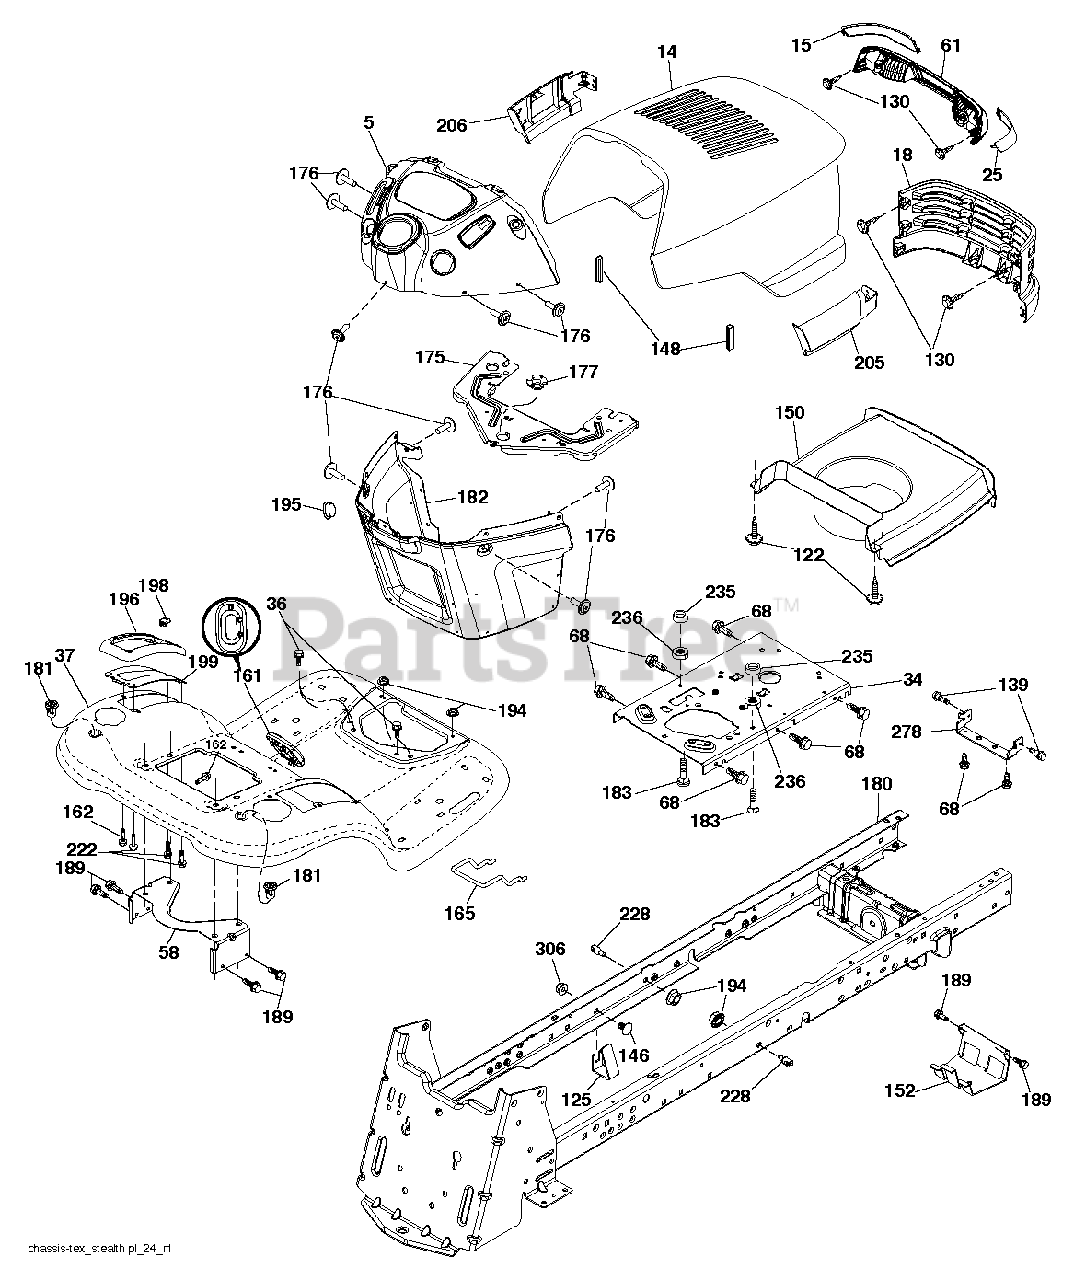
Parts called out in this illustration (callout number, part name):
5	DASH.STEALTH.SRV.RS.428
14	HOOD ASM.STEALTH.HOR-LOUV.667
15	LENS LH
18	GRILLE.STEALTH.GT.BLACK
25	LENS RH
36	SCREW 5/16"
58	BRKT.SUPPORT.FNDR/TANK
122	SCREW.WSHD.HEX10-32X5/8
125	Fuel Line Clip
130	SCREW.#10 X 0.750.BOS THREAD
139	BOLT, SHOULDER 5/16-18
146	BOLT.RDHD.SHT.SQNK.3
148	EXTRUSION BUMPER
152	SHIELD BROWNING
161	CONSOLE.FUEL.WINDOW.STGT.BLACK
162	SCREW.HI-LO.CONSOLE
165	SUPPORT.TANK.REAR.W/TE
175	CROSSMEMBER.
176	SCREW.#10-24X5/8.RN.QU
177	BUSHING,STEERING
180	CHASSIS.GT.SLOPED.DRAWBAR.
181	FEND/FTRST.PCH.CPH.NFW
182	DASH.LOWER.
183	BOLT.5/16-18X1-1/4 FULL THD
189	SCREW
194	NUT LOCK HEX FLANGE 5/16-18
195	PLUG.HOLE.DASH.LOWER.12V.BLK
198	INDICATOR.DECK.LIFT.RED
199	PLATE DECK LIFT
205	SKIRT.GRILLE.STEALTH.RH
206	SKIRT.GRILLE.STEALTH.LH
222	SCREW.1/4-20X5/8
228	STUD.FASTNER.W/ANTI-ROTATE
235	SPACER FENDER
236	NUT.CENTERLOCK.5/16-
278	BRKT.HOOD/MUFF.STEALTH
306	NUT LOCK FLG 3/8-16 UNC
